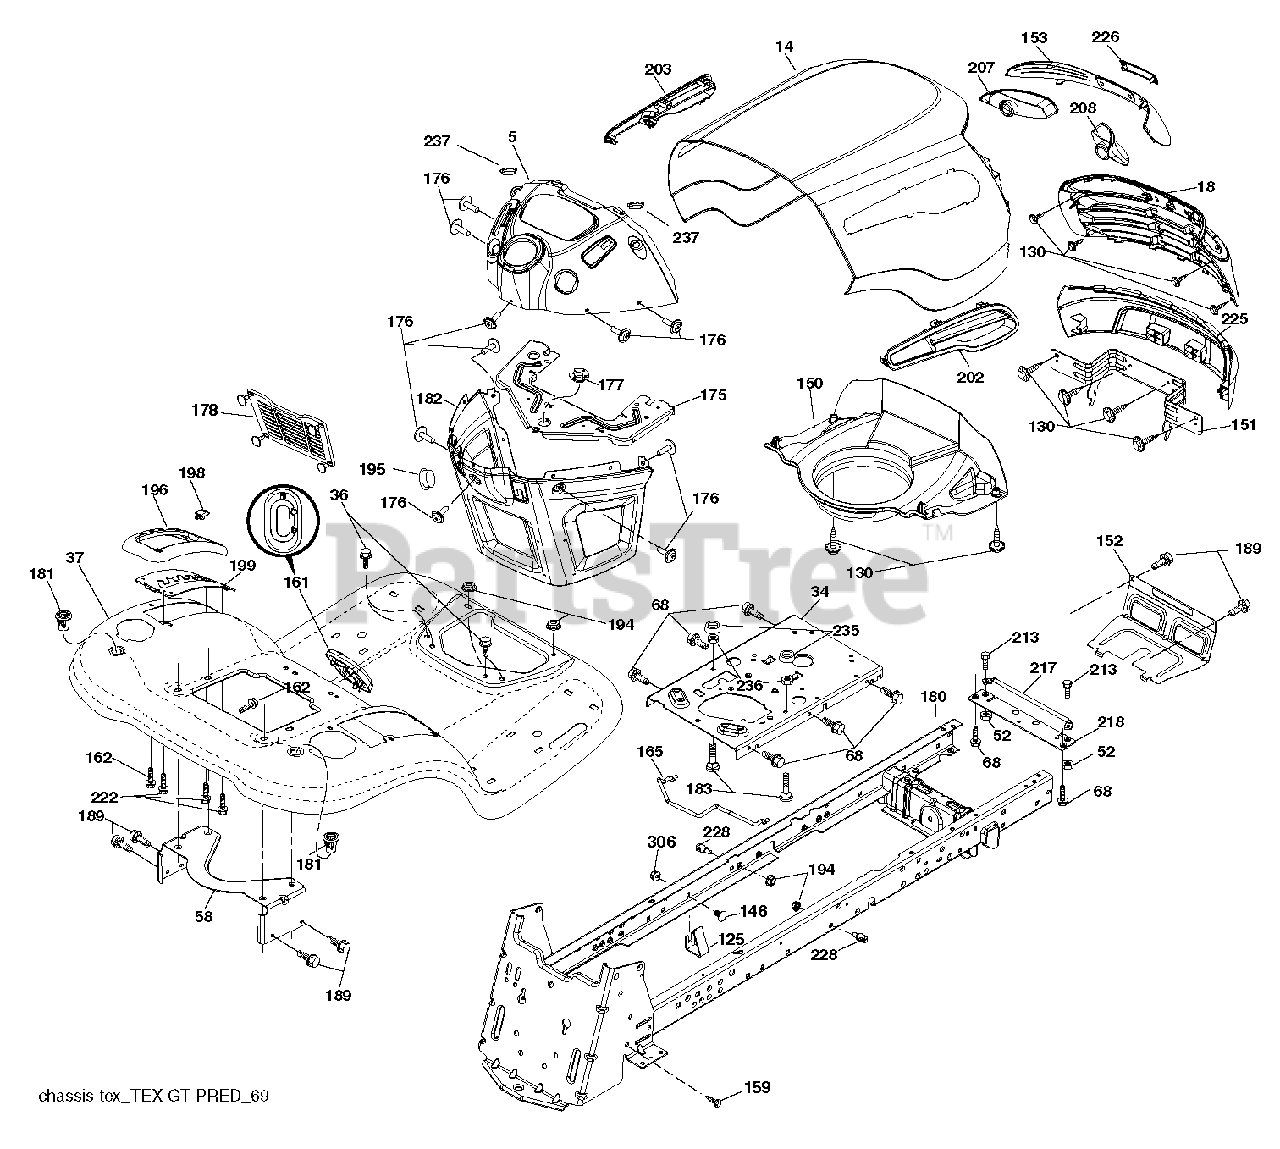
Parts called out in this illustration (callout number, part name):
36	SCREW 5/16"
52	LOCKNUT
58	BRKT.SUPPORT.FNDR/TANK
68	SCREW LT
125	Fuel Line Clip
130	SCREW.#10 X 0.750.BOS THREAD
146	BOLT.RDHD.SHT.SQNK.3
150	PREDATOR.YT.GT.HOOD.A
152	SHIELD BROWNING
159	SCREW, 3/8-16X3/4
161	CONSOLE.FUEL.WINDOW.STGT.BLACK
162	SCREW.HI-LO.CONSOLE
165	SUPPORT.TANK.REAR.W/TE
175	PLATE.CROSSMEMBER.HUSQ
176	SCREW.#10-24X5/8.RN.QU
177	BUSHING,STEERING
178	CARGO.ASM.NET.TXGT.W/C
180	CHASSIS.GT.SLOPED.DRAWBAR.
181	FEND/FTRST.PCH.CPH.NFW
182	DASH.LOWER.COMMON.12V.ADAPTOR
183	BOLT.5/16-18X1-1/4 FULL.THREAD
189	SCREW
194	NUT LOCK HEX FLANGE 5/16-18
195	PLUG.HOLE.DASH.LOWER.12V.BLK
198	INDICATOR.DECK.LIFT.RED
199	PLATE DECK LIFT
213	BOLT
217	ROD.PIVOT.HOOD
218	X-PIECE.HOOD.STOP.NON/
222	SCREW.1/4-20X5/8
228	STUD.FASTNER.W/ANTI-ROTATE
235	SPACER FENDER
236	NUT.CENTERLOCK.5/16-
237	PLUG.MOUNT.CARGO.BLK
306	NUT LOCK FLG 3/8-16 UNC
